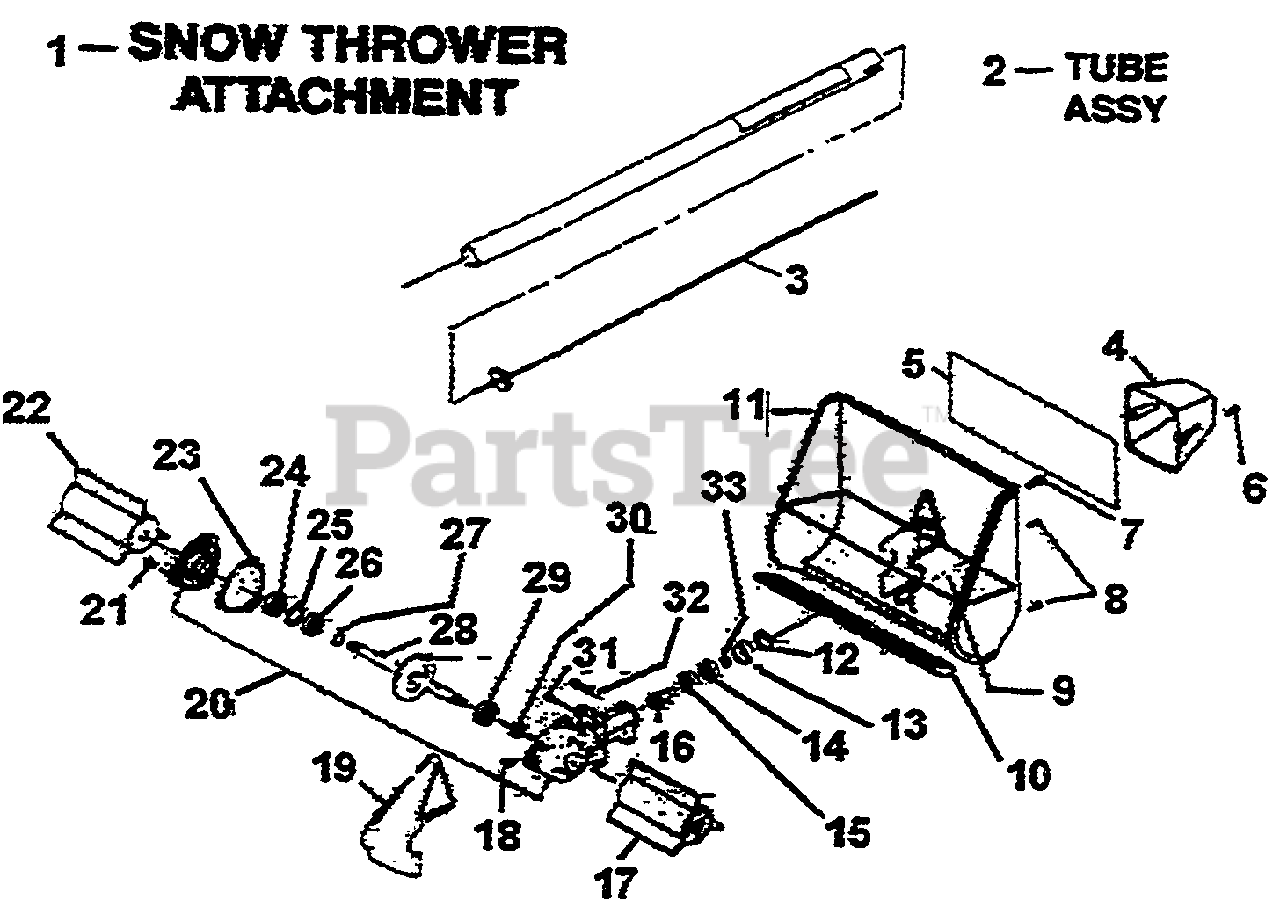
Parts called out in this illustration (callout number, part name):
1	SNOW THROWER ATTACHMENT
2	TUBE ASSY
3	FLEX CABLE
9	PLATE
10	SCRAPER BAR
12	SNAP RING
15	BEARING
16	PINION GEAR
17	ROTOR R.H.
20	GEAR CASE ASSY
22	ROTOR L.H.
28	SHAFT & GEAR
33	SNAP RING
